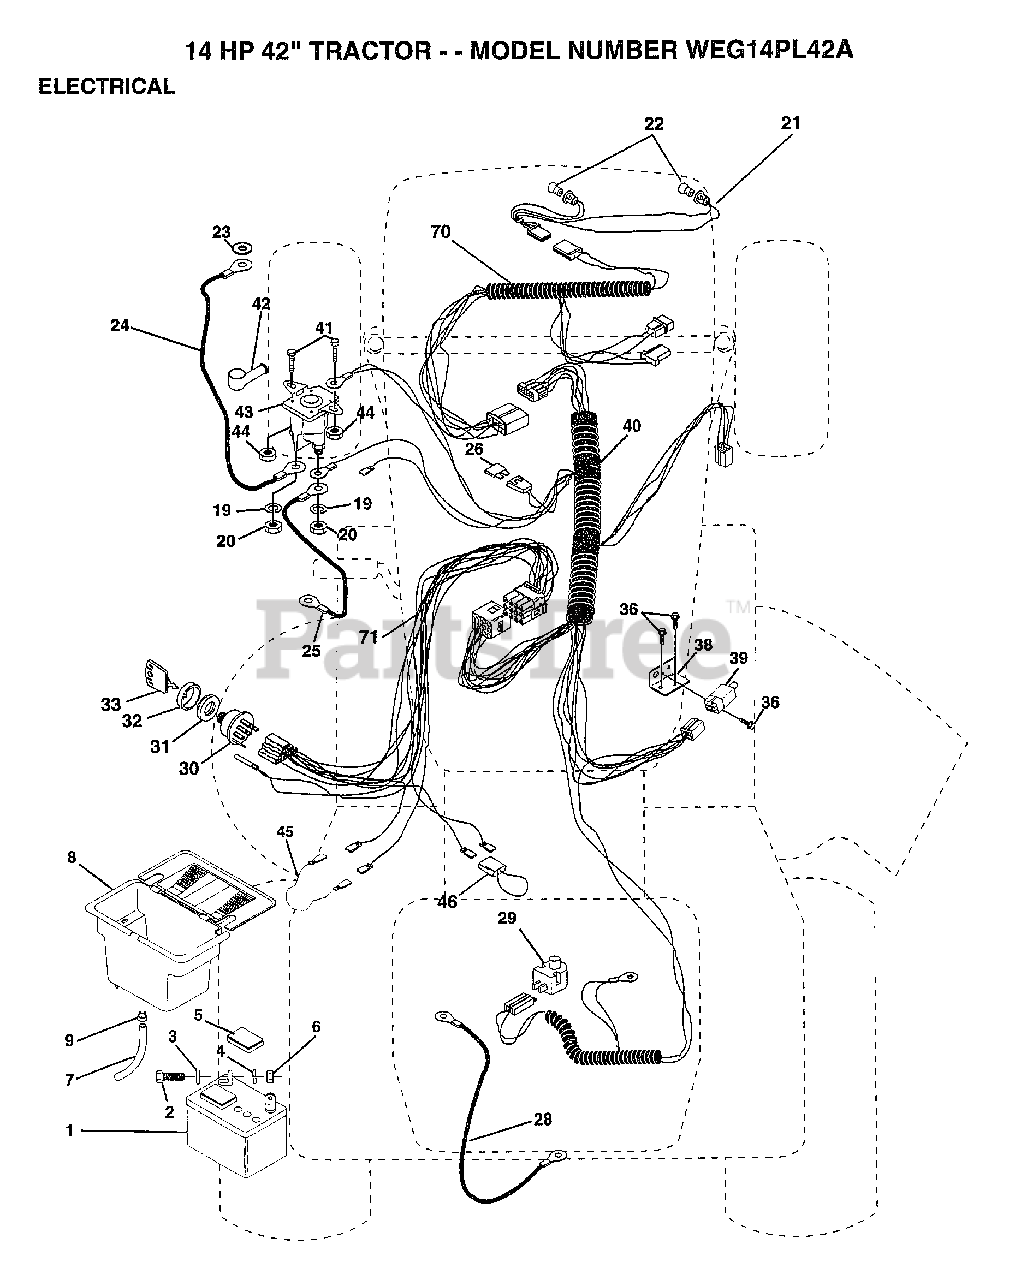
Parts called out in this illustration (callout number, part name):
2	BOLT LT
3	WASHER
4	LOCKWASHER
5	"CAP,BATTERY "
7	TUBE T
9	HOSE CLAMP T
18	CLIP PUSH - IN
20	NUT
21	"HARNESS,LIGHT SOC"
22	HEADLAMP BULB
23	LOCKWASHER
25	"CABLE T, BATTERY"
26	FUSE HYT
28	CABLE T
29	SWITCH SEAT
30	SWITCH IGN 4POS
31	NUT IGNITION
32	COVER KEY SWITCH
33	KEY
35	BRACKET LT
36	SCREW
37	SWITCH-INTER. GT
38	BRACKET SWITCH IN
39	SWITCH INTERLOCKT
40	HARNESS IGN B&S
41	BOLT HXHD FIN
44	NUT HXKEP 1/4X20
45	ADAPTER AMMETER
46	PROTECTION LOOP
69	ADAPTER.HARN.SERV
70	HARNESS ENGINE
71	HARNESS DASH LT
72	CLIP PUSHIN SPRIN
73	CLIP PUSH IN
